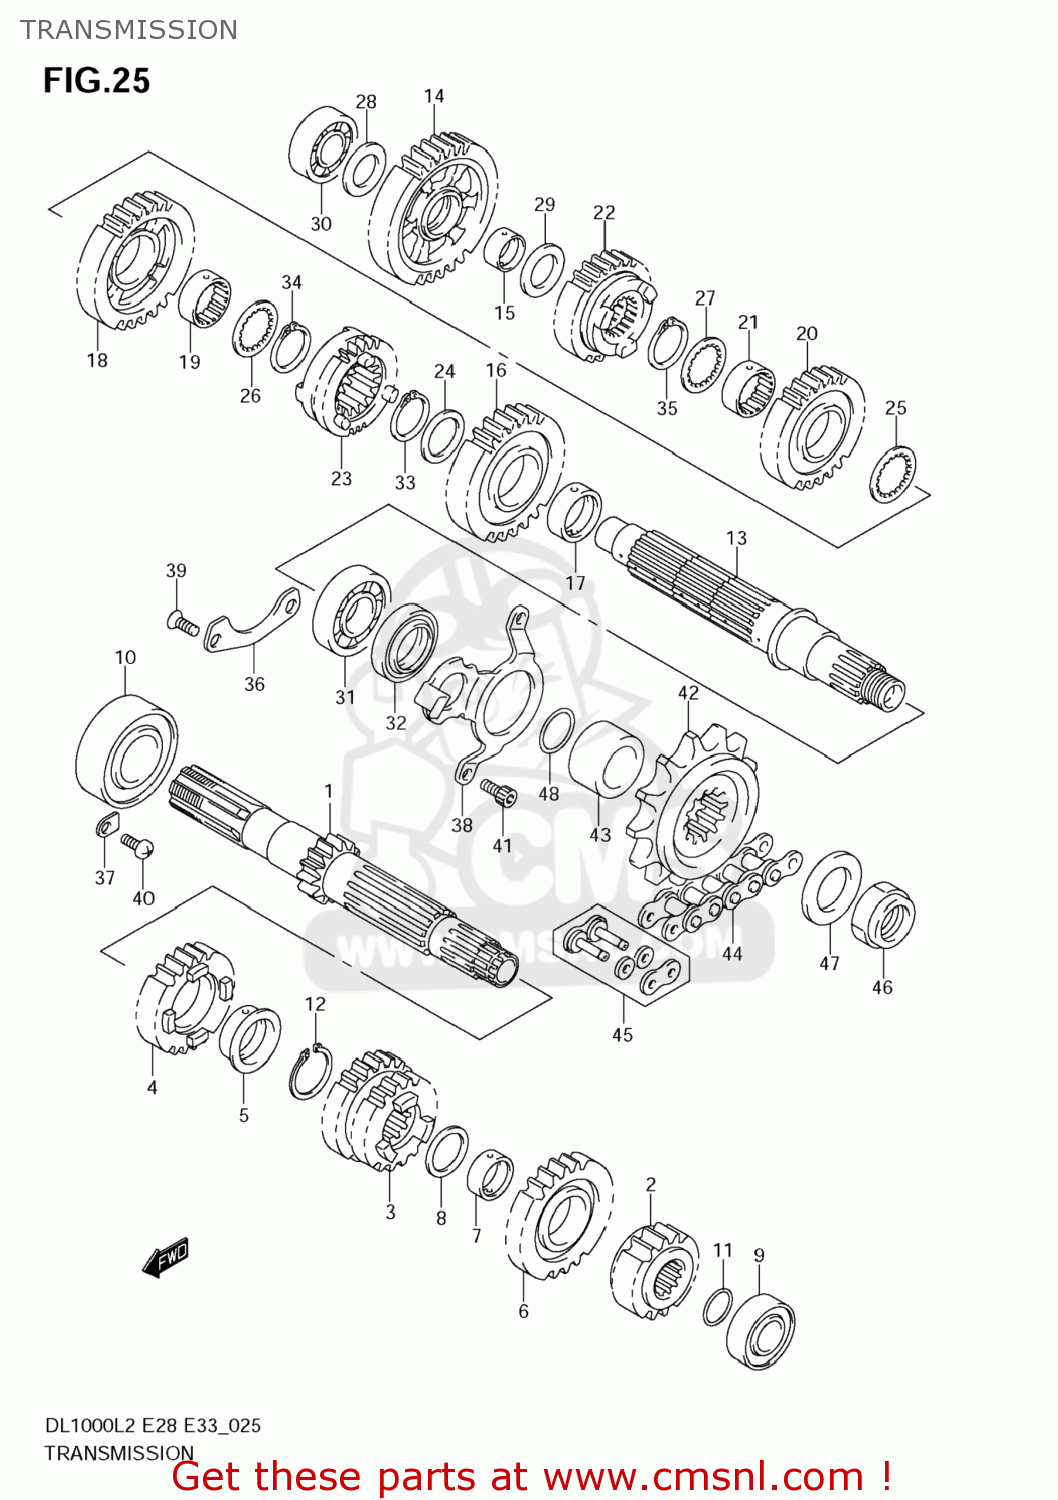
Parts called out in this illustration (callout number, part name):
1	SHAFT,COUNTER (NT:12)
2	GEAR,2ND DRIVE(NT:15)
3	GEAR,3RD & 4TH DRIVE(NT:18/22)
4	GEAR,5TH DRIVE(NT:23)
5	BUSH,5TH DRIVE GEAR
6	GEAR,6TH DRIVE(NT:23)
7	BUSH,6TH DRIVE GEAR
8	SHIM(22X30X1)
9	BEARING(20X47X14)
10	BEARING(25X62X17)
11	O RING(D:1.9,ID:16.6)
12	CIRCLIP
13	SHAFT,DRIVE
14	GEAR,1ST DRIVEN
15	BUSH
16	GEAR,2ND DRIVEN(NT:29)
17	BUSH,2ND DRIVEN GEAR
18	GEAR,3RD DRIVEN(NT:27)
19	BUSH,3RD DRIVEN GEAR
20	GEAR,4TH DRIVEN(NT:27)
21	BUSH,3RD DRIVEN GEAR
22	GEAR,5TH DRIVEN(NT:25)
23	GEAR,6TH DRIVEN(NT:21)
24	WASHER(27X36X1)
25	WASHER,LOCK
26	WASHER,3RD & 4TH DRIVEN
27	WASHER,3RD & 4TH DRIVEN
28	SHIM(20X34X1)
29	SHIM(22X34X1)
30	BEARING(20X52X15)
31	BEARING(28X68X20)
32	SEAL,OIL(38X52X8)
33	CIRCLIP
34	CIRCLIP
35	CIRCLIP
36	RETAINER,DRIVE SHAFT BEARING
37	RETAINER
38	RETAINER,DRIVE SHAFT OIL SEAL
39	SCREW(6X12)
40	SCREW
41	BOLT
42	SPROCKET,ENGINE(17T)
43	SPACER,ENGINE SPROCKET
44	CHAIN ASSY (RK525SMOZ7) (GSX-R600K4/K5L:112-110)
45	JOINT SET
46	NUT
47	WASHER(25X41X3)
48	O RING(D:2.4,ID:23.7)
